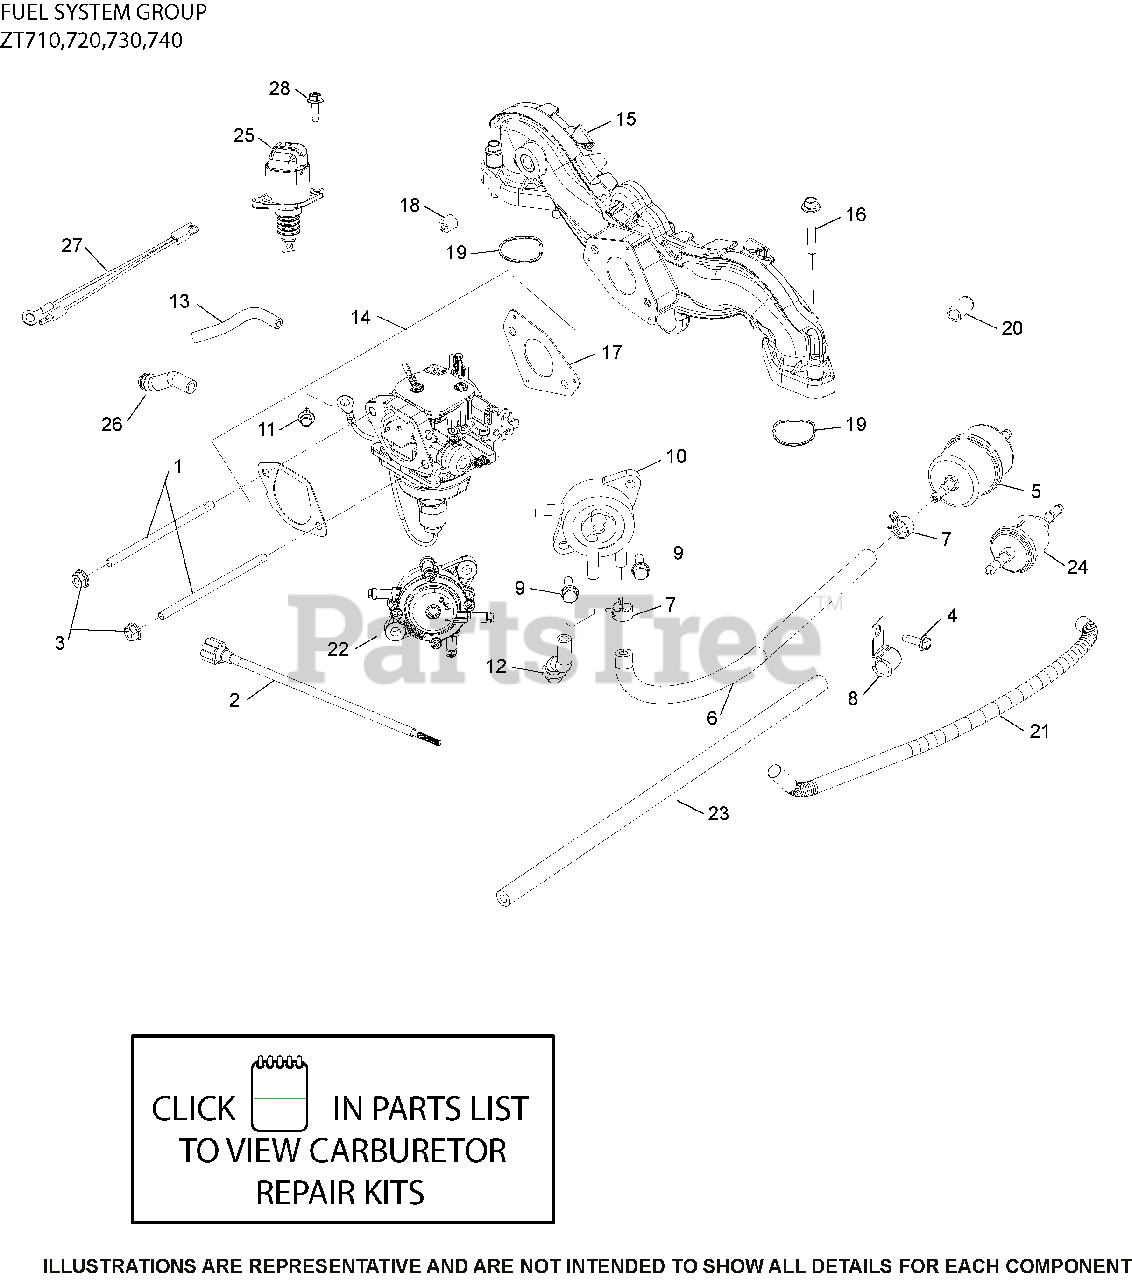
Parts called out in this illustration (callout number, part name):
3	NUT, FLG M6X1.0
5	FILTER, FUEL
6	HOSE,LW PERM.FUEL 24.00"-USE 25 111 81-S
7	CLAMP SPRING HOSE
8	CLIP, CABLE
9	SCREW, TAP M6X1.7X18
11	SCREW, THREAD FORMING
12	HOSE, PULSE PUMP
14	KEIHIN CARB KIT COMPLETE (STD)
15	KIT, INTAKE MANIFOLD
16	SCREW, FLG M6X1.0X40
17	GASKET, CARBURETOR
18	PLUG, CTSK PIPE 1/8"
19	O-RING, INTAKE PORT (PIM)
22	PUMP, FUEL (PULSE)
28	SCREW, THREAD FORMING
